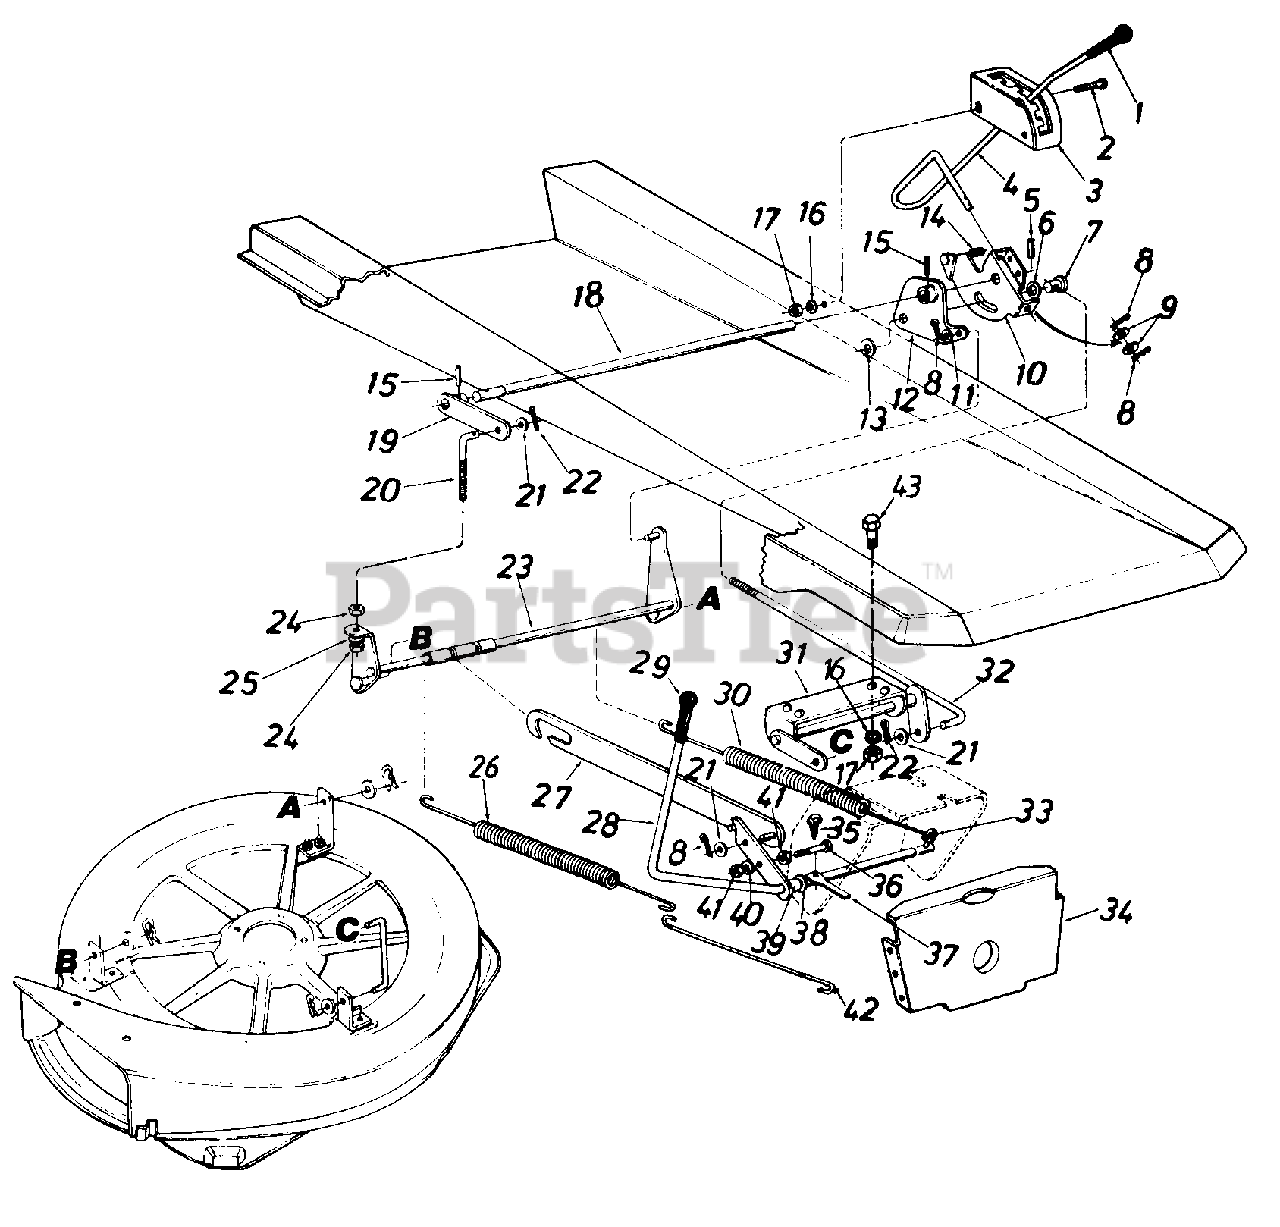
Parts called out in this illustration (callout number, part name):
2	Truss Mach. Scr. 5/16-18 x .75" Lg.
5	Spring Pin Spir. 3/16" Dia. x 1.50" Lg.
6	Fl-Wash. .385" I.D. x .87" O.D.
7	Adj. Ferrule Deck Lift Handle
8	Cotter Pin 1/8" Dia. x 1.00" Lg.
9	Fl-Wash. .531" I.D. x .930" O.D.
10	Deck Lift Handle Retainer Ass'y.
11	Fl-Wash. .385" I.D. x .87" O.D.
12	Deck Lift Brkt. Ass'y. L.H.
13	Fl-Wash. .635" I.D. x 1.04" O.D.
14	Compression Spring .50" Dia. x 1.0" Lg.
15	Spring Pin Spir. 1/4" Dia. x 1.50" Lg.
16	L-Wash. 5/16" I.D.
17	Hex Nut 5/16-18 Thd.
18	Rear Hgt. Adj. Shaft
19	Deck Lift Brkt. Ass'y. R.H.
20	Deck Adj. Scr. 3/8-16 Thd.
21	Fl-Wash. .385" I.D. x .87" O.D.
22	Intern. Cotter Pin 1/2" Dia.
23	Deck Link Ass'y. Rear
24	Hex Nut 3/8-16 Thd.
25	L-Wash. 3/8" I.D.
26	Extension Spring .73" O.D. x 13.84" Lg.
27	Deck Drive Control Bracket
28	Blade Engagement Lever Ass'y.
30	Extension Spring .73" O.D. x 13.84" Lg.
31	Deck Lift Ass'y. Front
32	Deck Lift Connecting Rod
33	Clevis Pin Special .250" Dia.
34	Pivot Bar Bracket
35	Hex TT-Tap Scr. 1/4-20 X .75"
36	Hex Bolt 5/16-18 x 1.50" Lg. (Grade 5)
37	Switch Actuator
38	Fl-Wash. .531" I.D. x .930" O.D.
39	Spacer.511" I.D. x.70" O.D. x.38" Lg.
40	L-Wash. 5/16" I.D.
41	Hex Nut 5/16-18 Thd.
42	Spring Hook
43	Hex Bolt 5/16-18 x .75" Lg.
